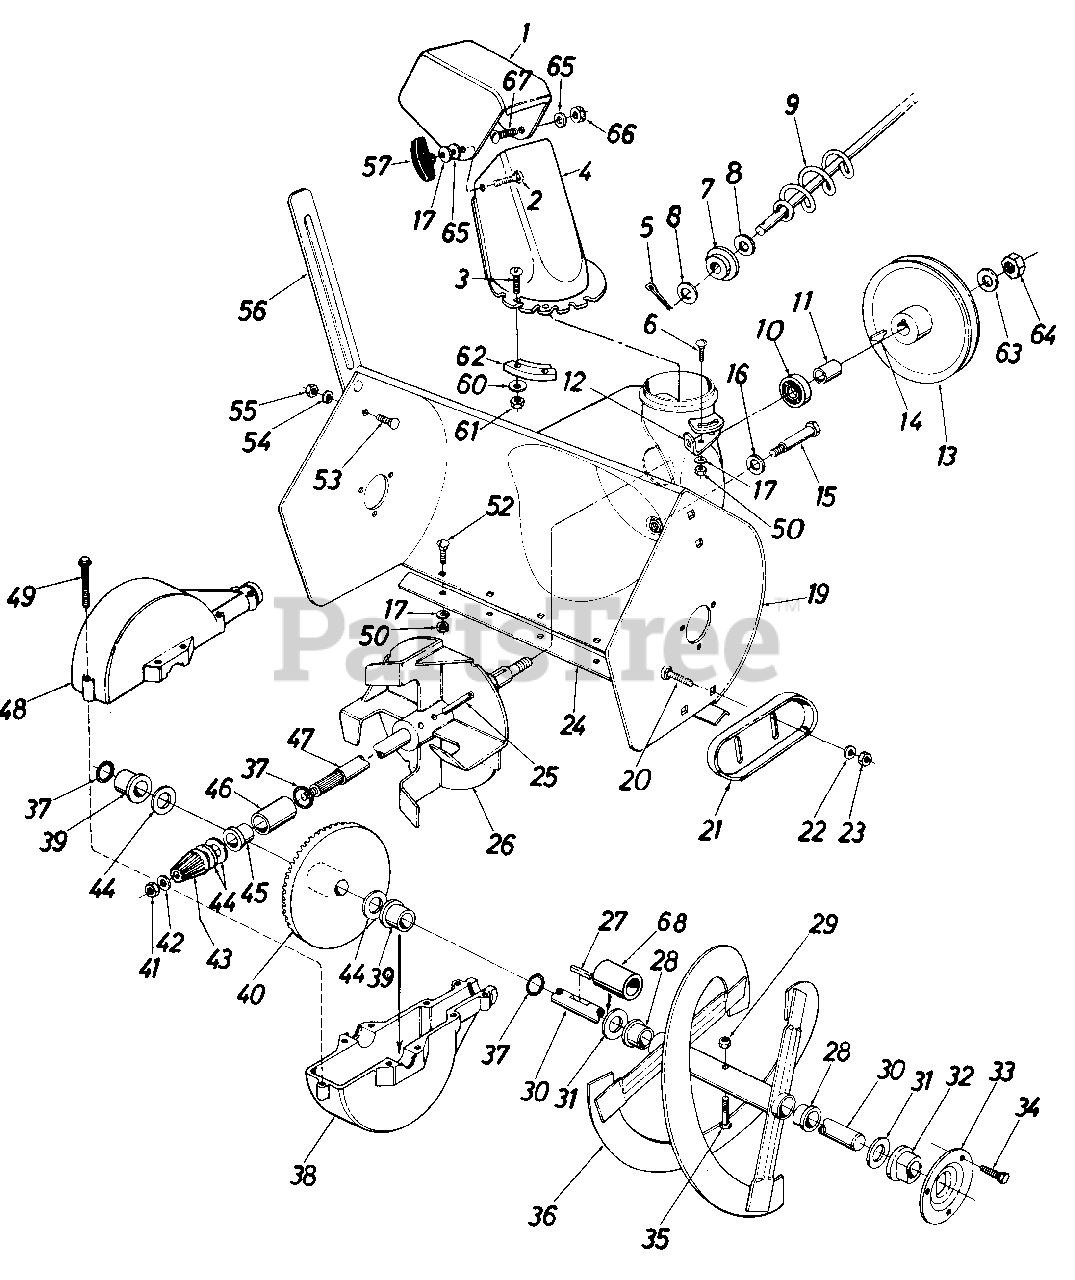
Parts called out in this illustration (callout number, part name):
1	Upper Chute
2	Carriage Bolt 5/16-18 x 1.0"
3	Truss Mach. Scr. 1/4-20 x .75"
4	Lower Chute
5	Cotter Pin
6	Carriage Bolt 5/16-18 x .75"
7	Bushing
8	Fl-Wash. .385 I.D. x .62" O.D.
9	Chute Crank Ass'y.
10	Ball Brg. .62" I.D. x 1.38" O.D.
11	Spacer .63" I.D. x .88" O.D. x .900" Lg.
12	Chute Crank Brkt.
13	1/2 V-Pulley .625" I.D. x 7.50" O.D.
13	5/8" "V"-Pulley .625" I.D. x 7.50" O.D.
14	#61 Hi-Pro Key 3/16" x 5/8" Dia.
15	Shld. Bolt .50" Dia. x 2.11"
16	Bell-Wash. .40" I.D. x .88" O.D. x .06
17	Bell-Wash. .34" I.D. x .88" O.D.
19	26" Blower Housing Ass'y.
20	Carriage Bolt 3/8-16 x .62"
21	Slide Shoe
22	Bell-Wash. 3/8" I.D.
23	Hex Jam Nut 3/8-16 Thd.
24	20" Shave Plate
24	24" Shave Plate
24	26" Shave Plate
25	Spring Pin Spiral 1/4" Dia. x 1.50" Lg.
26	11" Dia. Blower Fan Ass'y.
27	Sq. Key 3/16" x 1.5" Lg.
28	Flange Brg. .75" I.D. x .88" O.D.
29	Hex Ins. L-Nut 5/16-18
30	Spiral Axle
31	Fl-Wash. .75" I.D. x 1.50" O.D. x .06
32	Flange Brg. w/Flats .755" I.D.
33	Bearing Housing
34	Hex Wash. Hd. Self-Tap Scr. 5/16-24 x .62" Lg.
35	Hex Bolt 5/16-18 x 1.50" Lg.
36	20" Spiral Ass'y.-L.H.
36	20" Spiral Ass'y.-R.H.
36	24" & 26" Spiral Ass'y.-L.H.
36	24" & 26" Spiral Ass'y.-R.H.
37	O-Ring-3/4" I.D.
38	Bevel Gear Housing-Lower Half
39	Plastic Flange Brg. .755" I.D.
40	Bevel Gear
41	Hex Cent. L-Nut 5/16-24 Thd.
42	Fl-Wash. .34" I.D. x .62" O.D. x .06
43	Pinion Gear
44	Fl-Wash. .75" I.D. x 1.25" O.D. x .06
45	Flange Brg. .755" I.D.
46	Sleeve Brg. .755" I.D.
47	Blower Axle
48	Bevel Gear Housing- 0 Upper Half
49	Hex Wash. Hd. Self-Tap Scr. 1/4-20 x 1.00" Lg.
50	Hex Nut 5/16-18 Thd.
52	Carriage Bolt 5/16-18 x .62" Lg.
53	Carriage Bolt 5/16-18 x .62" Lg.
54	L-Wash. 5/16" I.D.
55	Hex Nut 5/16-18 Thd.
56	Drift Cutter Bar
60	Fl-Wash. 1/4" I.D.
61	Hex L-Nut 1/4-20 Thd.
62	Chute Flange Keeper
63	Fl-Wash. .64" I.D. x .94" O.D. x .06
64	Hex Jam Nut 5/8-18 Thd.
65	Fl-Wash. .344 I.D. x 1.125 O.D.
66	Hex L-Nut 5/16-18 Thd.
67	Truss Mach. Scr. 5/16-18 x 75" Lg.
68	Spacer
